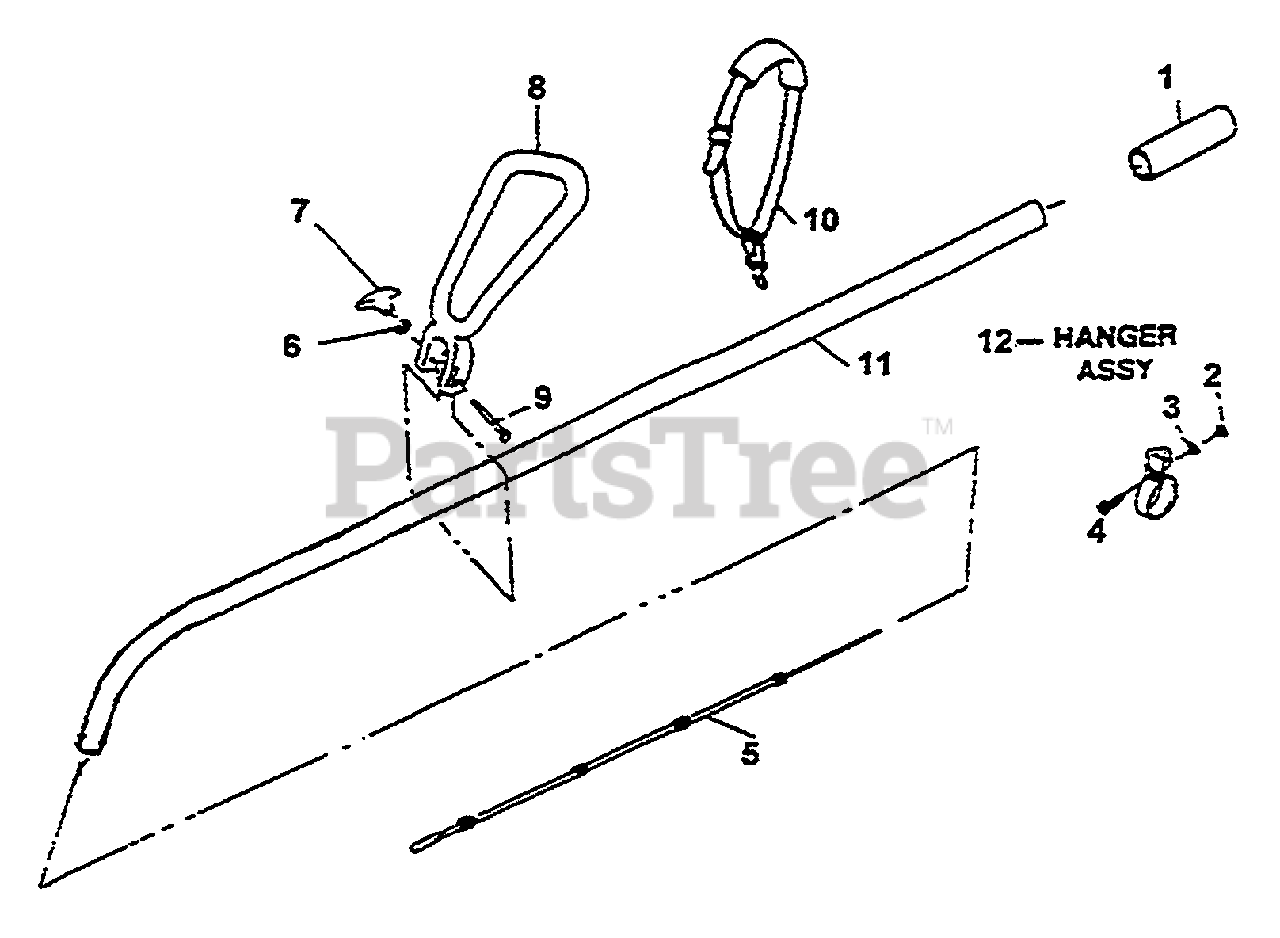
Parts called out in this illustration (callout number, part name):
1	FOAM GRIP
5	FLEX SHAFT
7	KNOB
8	ASSIST HANDLE
9	BOLT
11	TUBE ASSY
12	HANGER ASSY
